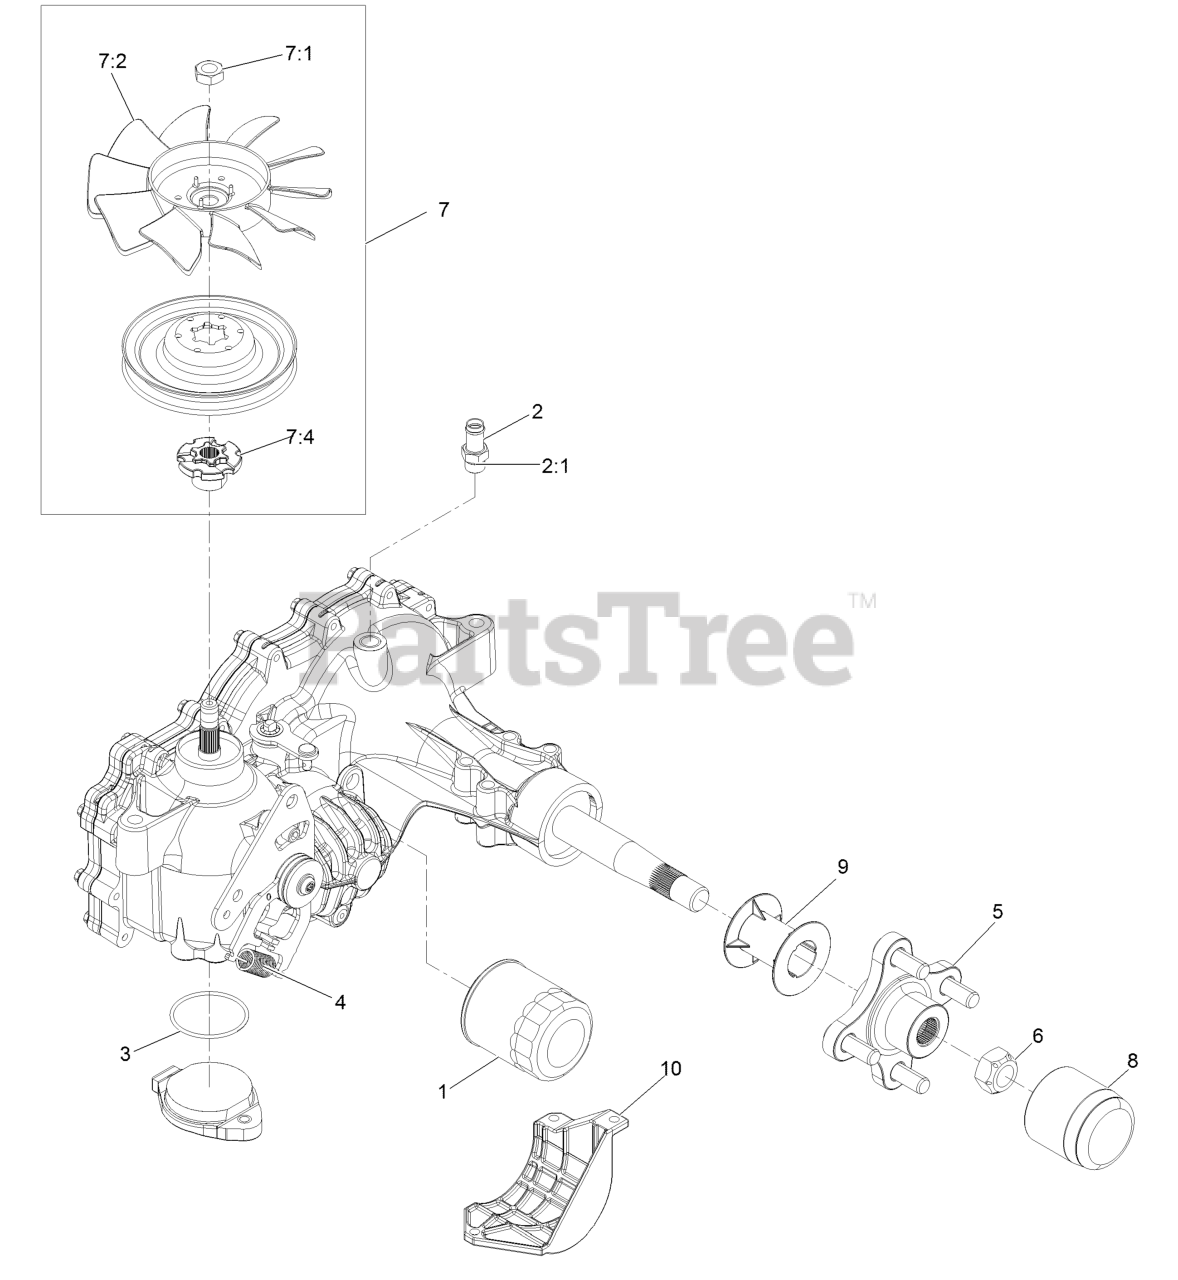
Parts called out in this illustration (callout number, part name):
1	Filter-Hydraulic
2	Adapter-Straight
2:1	O-Ring
3	O-Ring-Charge Seal Cover
5	Hub-Offset
6	Nut-Hub
7	Fan And Pulley Kit
7:4	Hub-Pulley
8	Cap-Axle, Long
9	Tube-Axle
10	Guard-Filter, LH
99	Seal Kit
